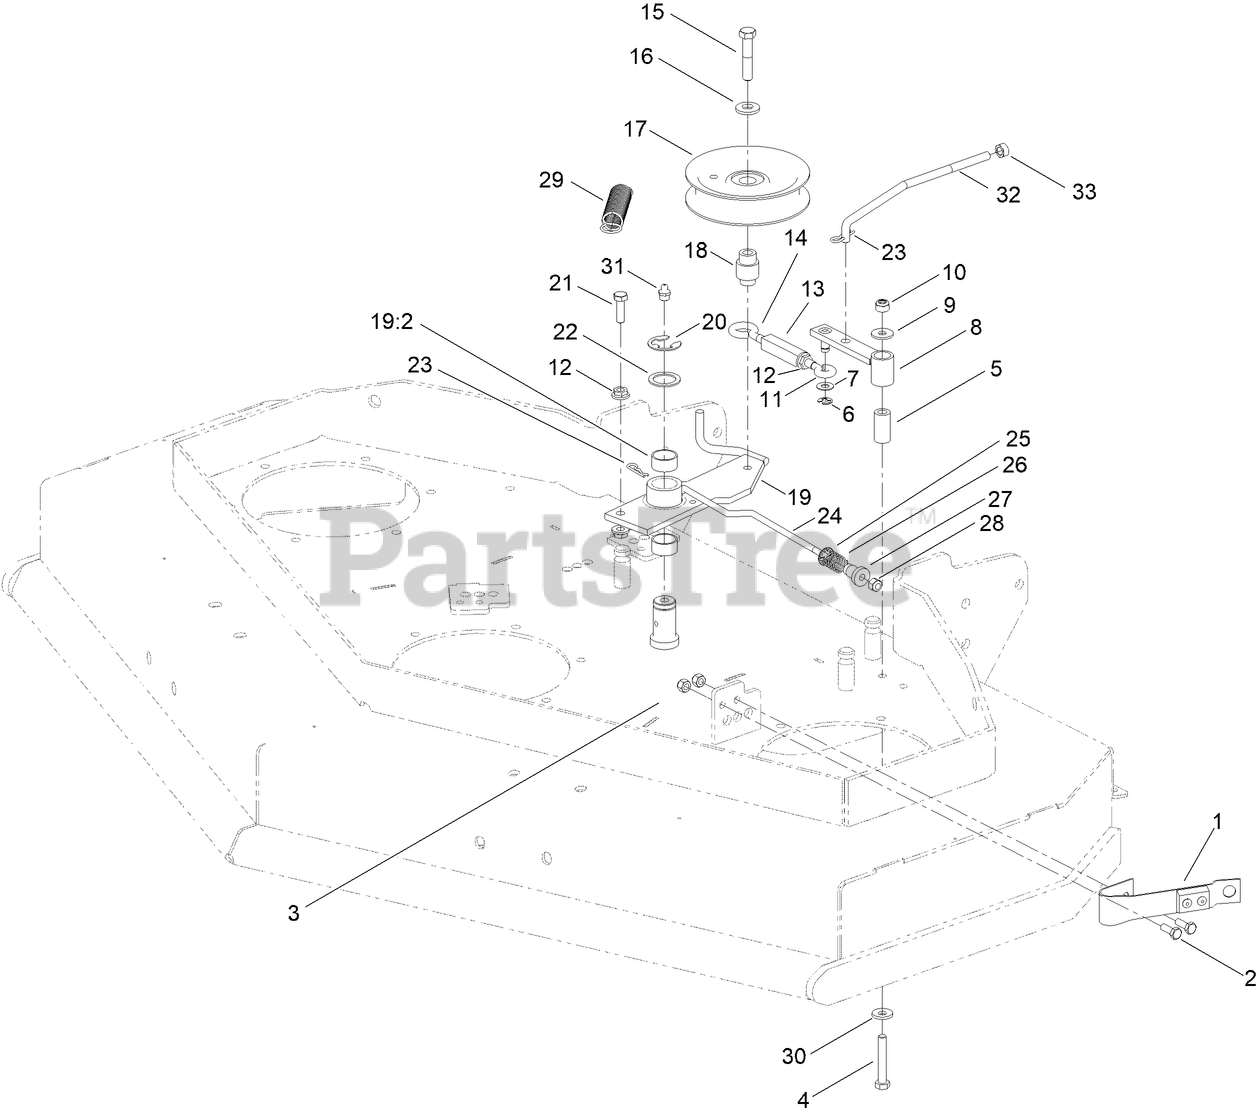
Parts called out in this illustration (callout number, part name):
1	PAD AND SPRING ASM
2	SCREW-HH
3	NUT-LOCK, NI
4	SCREW-HH
5	TUBE-PIVOT
6	RING-RETAINING, EXT
7	WASHER-PLAIN
8	ARM-ASSIST, 32/36
9	WASHER
10	NUT-NYLOC
11	EYEBOLT-THREAD, RH
12	NUT-HF
13	BODY-TURNBUCKLE
14	EYEBOLT-THREAD, LH
15	SCREW-HH
16	WASHER-BELLEVILLE
17	PULLEY-IDLER, FLAT
18	BUSHING-ENGAGEMENT
19	IDLER ARM ASM
19:2	SLEEVE-BEARING
20	RING-RETAINING, EXT
21	SCREW-HH
22	WASHER-SPINDLE
23	PIN-COTTER
24	ROD-BRAKE
25	RING-PUSH ON
26	SPRING-COMPRESSION
27	SPACER-FLANGED
28	NUT-LOCK, NI
29	SPRING-EXTENSION
30	WASHER-SPRING
31	FITTING-STRAIGHT
32	ROD-LINKAGE, DRIVE
